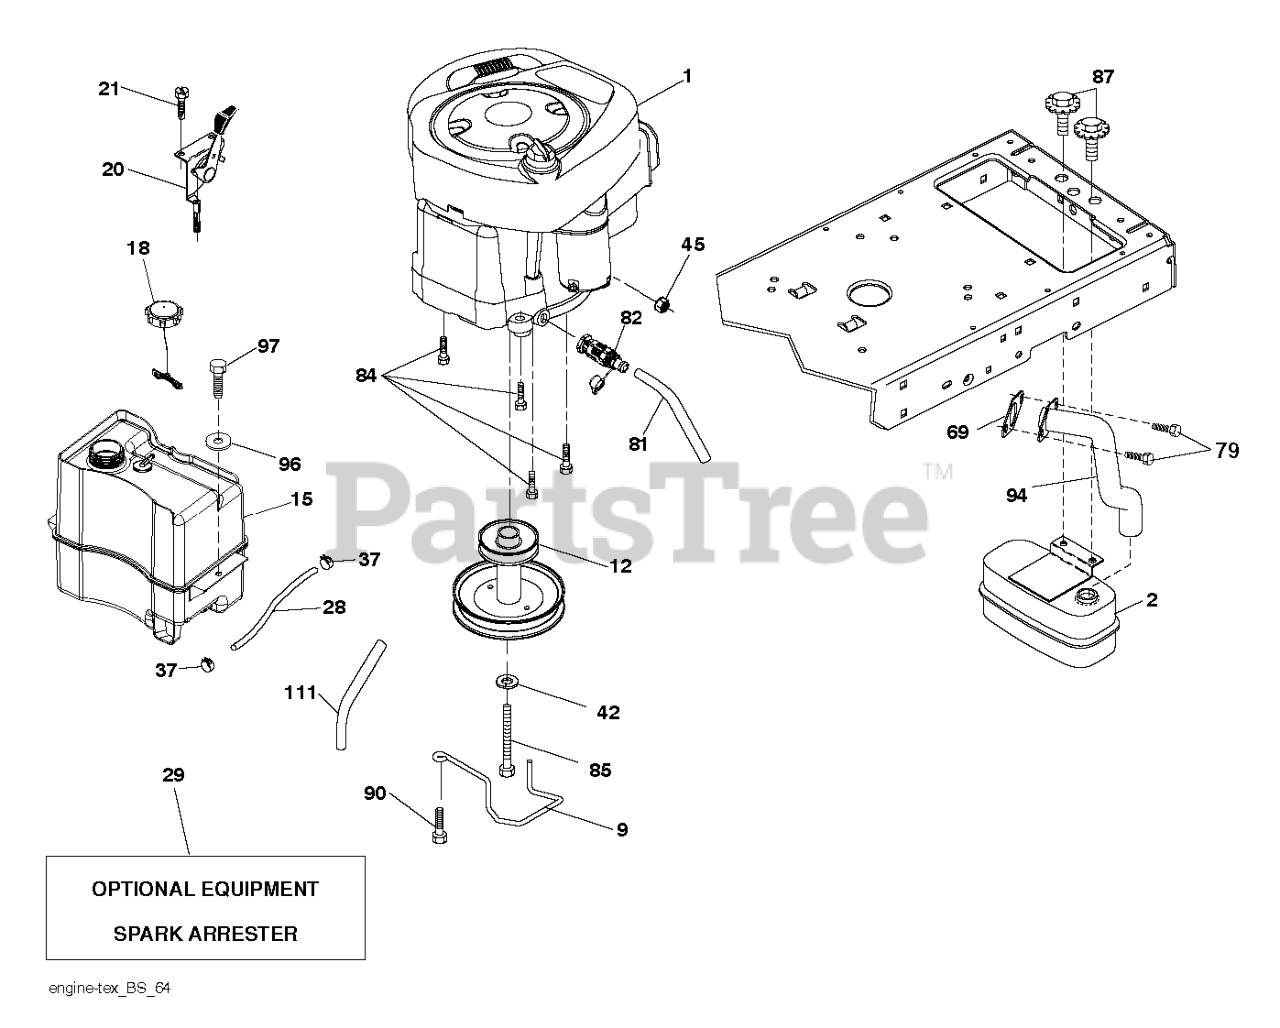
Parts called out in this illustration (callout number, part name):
2	MUFFLER.ASM.SNGL.XTNDED.DFLCTR
9	KEEPER.BELT.ENGINE.3.25 (3 2)
12	PULLEY ENGINE
15	TANK.ASM.FRT.2.5 GAL.W/CAP.EPA
18	CAP.FUEL.2 WAY VENT
20	CONTROL.TH/CK.COBRA.KO
21	SCREW.#10 X 0.750.BOS
28	LINE.FUEL.20"FRONT.EMI
29	KIT.SPARK ARRESTOR 794945 B&S
37	HOSE CLAMP
42	LOCKWASHER
45	NUT
69	REPL BY 532 27 22-93
79	SCREW.SOCKET HD.5/16-1
81	TUBE, DRAIN OIL ASM.
82	VALUE.OIL.DRAIN
84	SCREW.3/8-16
85	BOLT HEX 7/16-20X4-1/4"
87	BOLT.5/16-18UNCX3/4 W/SEMS.BLK
90	SCREW 3/8-16X1
94	RP.EXHAUST.TUBE.B&S.28/31
96	WASHER
97	SCREW HEXWSHR 1/4-20X3/4
111	RP PURGE LINE
